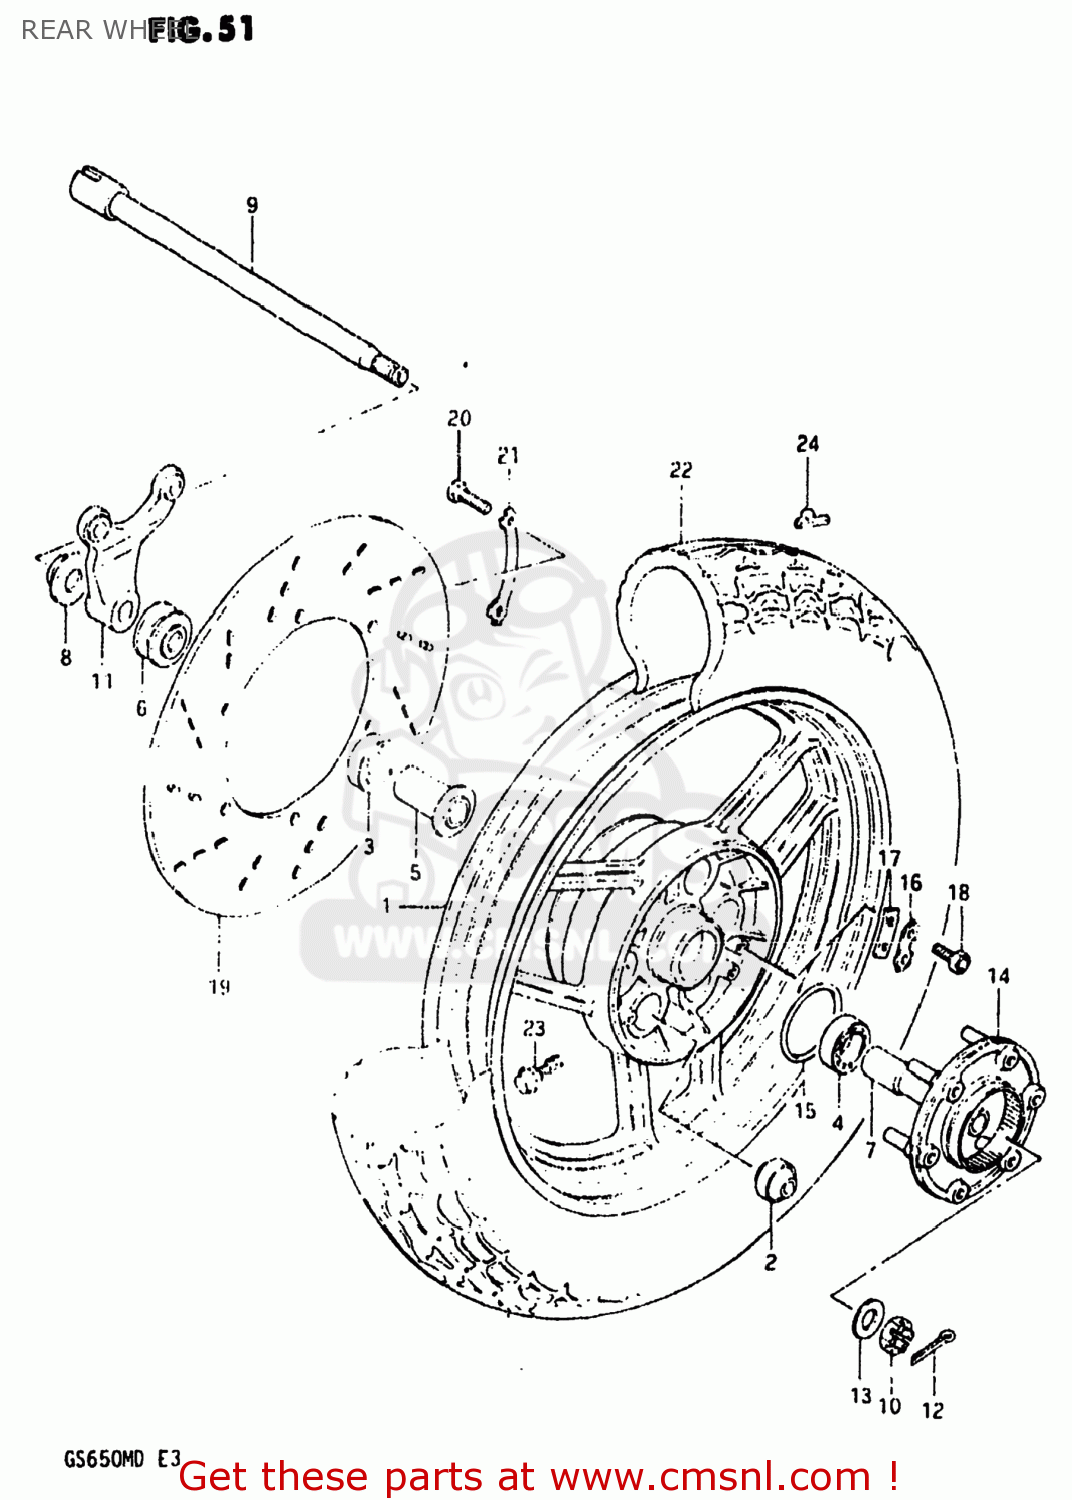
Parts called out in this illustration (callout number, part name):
1	WHEEL SET,REAR
2	BUSH
3	BEARING
4	BEARING
5	SPACER,REAR HUB BEARING
6	SPACER,REAR AXLE
7	SPACER,REAR AXLE,LEFT
8	SPACER,REAR AXLE,RIGHT
9	AXLE,REAR
10	NUT
11	BRACKET,REAR CALIPER
12	PIN,COTTER
13	WASHER(16.5X36X3.2)
14	JOINT ASSEMBLY,REAR HUB DRUM
15	O RING(D:2.1,ID:65)
16	WASHER
17	WASHER,THRUST(T:1.6)
18	BOLT(6X16)
19	DISC,REAR BRAKE
20	BOLT(8X28)
21	WASHER
22	TIRE
23	VALVE ASSEMBLY,WHEEL RIM,J
24	BALANCER,WHEEL
